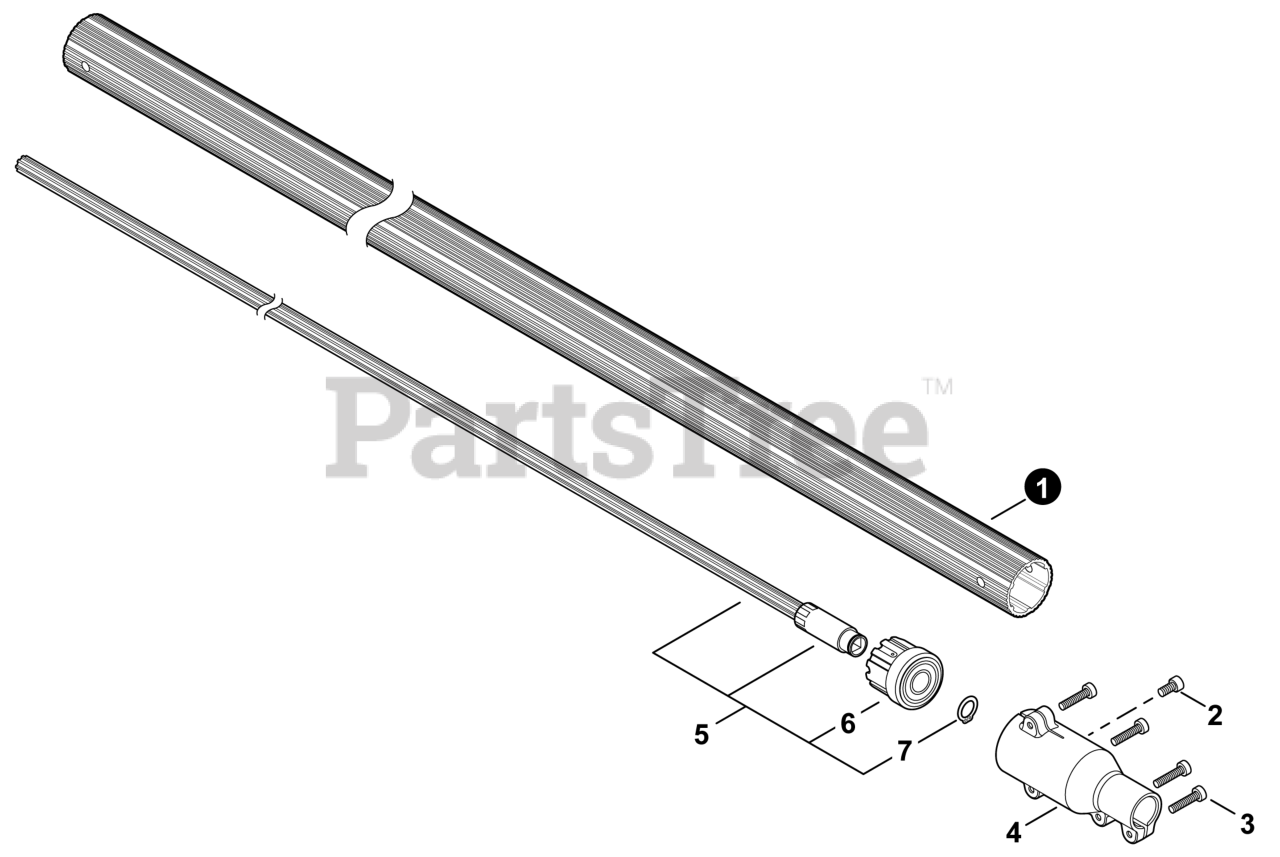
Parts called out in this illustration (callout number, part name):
1	PIPE, MAIN - ORANGE
2	BOLT, TORX 5x16
3	BOLT, TORX 5x20
4	COUPLING, MAIN PIPE
5	DRIVESHAFT ASSY, LOWER
6	HOLDER ASSY, BEARING
7	RING, RETAINING
